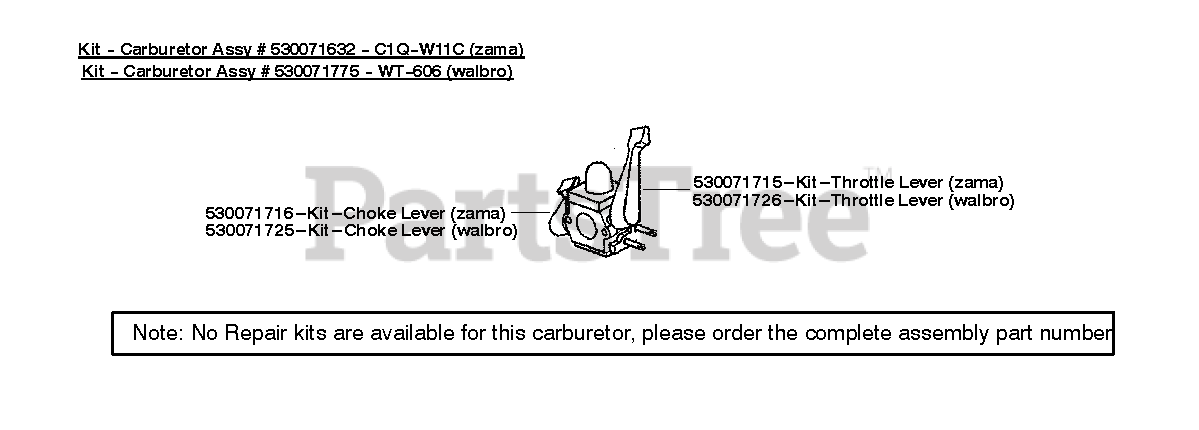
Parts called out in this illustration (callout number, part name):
1	CARB
2	CARBURETTOR
3	KIT CHOKE LB25 ZAMA
5	THROTTLE KIT ZAMA
